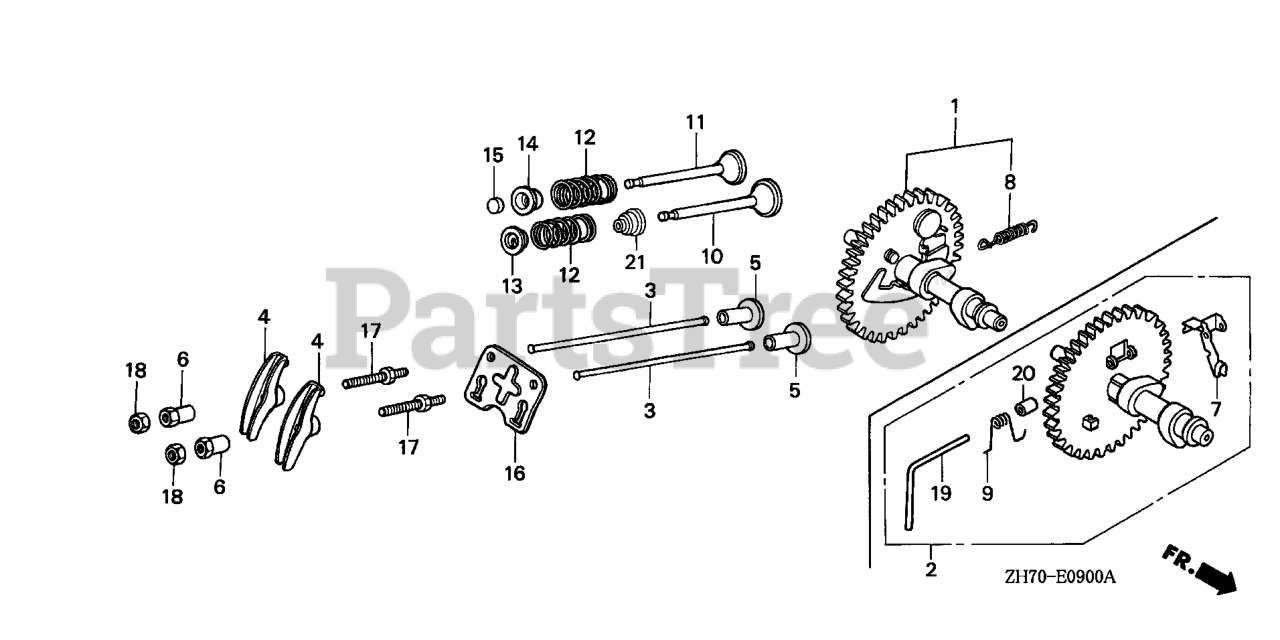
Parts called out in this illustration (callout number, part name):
1	CAMSHAFT ASSY.
3	ROD, PUSH
4	ARM, VALVE ROCKER
5	LIFTER, VALVE
6	PIVOT, ROCKER ARM
8	SPRING, WEIGHT RETURN
10	VALVE, IN.
11	VALVE, EX. (STELLITE)
11	VALVE, EX.
12	SPRING, VALVE
13	RETAINER, VALVE SPRING (EXHAUST SIDE)
14	RETAINER, EX. VALVE SPRING
15	ROTATOR, VALVE
16	PLATE, PUSH ROD GUIDE
17	BOLT, PIVOT (8MM)
18	NUT, PIVOT ADJ.
21	SEAL, VALVE STEM
